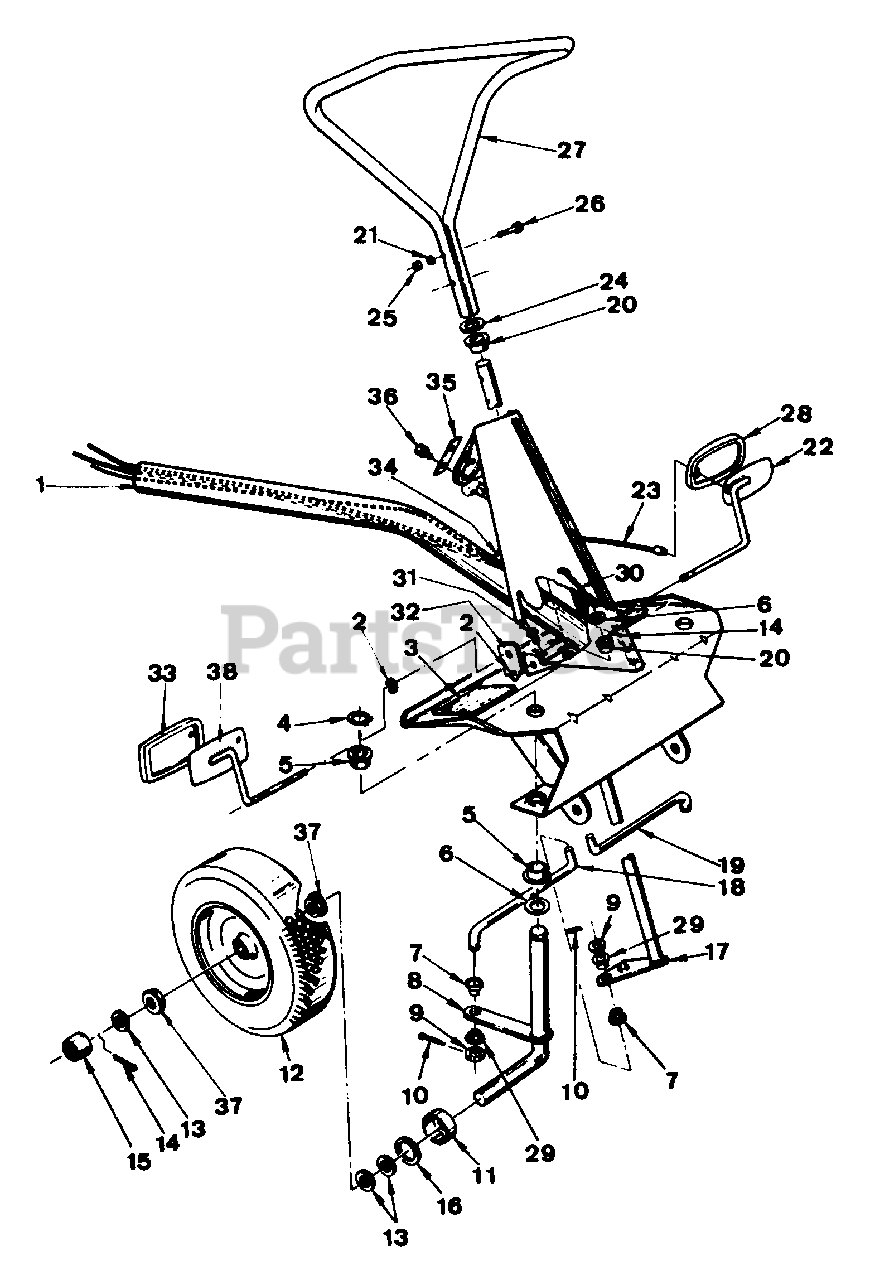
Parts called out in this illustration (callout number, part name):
1	Front Axle
2	Retaining Ring
3	PAD, Foot
4	Retaining Ring
5	Bearing
6	Washer
7	bearing Half
8	King Pin, R.H.
9	3/8-SAE Washer
10	3/16 x 3/4 Cotter Pin
11	Dust Cap
12	Wheel Assembly (Complete)
13	Washer
14	5/32 x 1 Cotter Pin
15	Hub Cap
16	Felt Washer
17	Storing Shaft
18	Tie Rod, R.H.
19	Tie Rod, L.H.
20	Nylon bushing
21	1/4 Internal Tooth Lock Washer
22	Pedal
23	Cable, 30" Comet
23	Cable, 26" Comet
24	Shim Washer
25	1/4-28 Hex Nut
26	Handle Screw
27	Steering Wheel
28	Pedal Pad
29	Bearing Half
30	Brake Cable, 26" Comet
30	Brake Cable, 30" Comet
31	5/16-18 x 5/8 HW ST
32	brake Mount
33	Brake Pad
34	Throttle Control, 8 M.P.
34	Throttle Control, 5 M.P.
35	Throttle Plate
36	10/24 x 5/8 WFCS ST
37	Ball bearing
38	Brake Pedal
